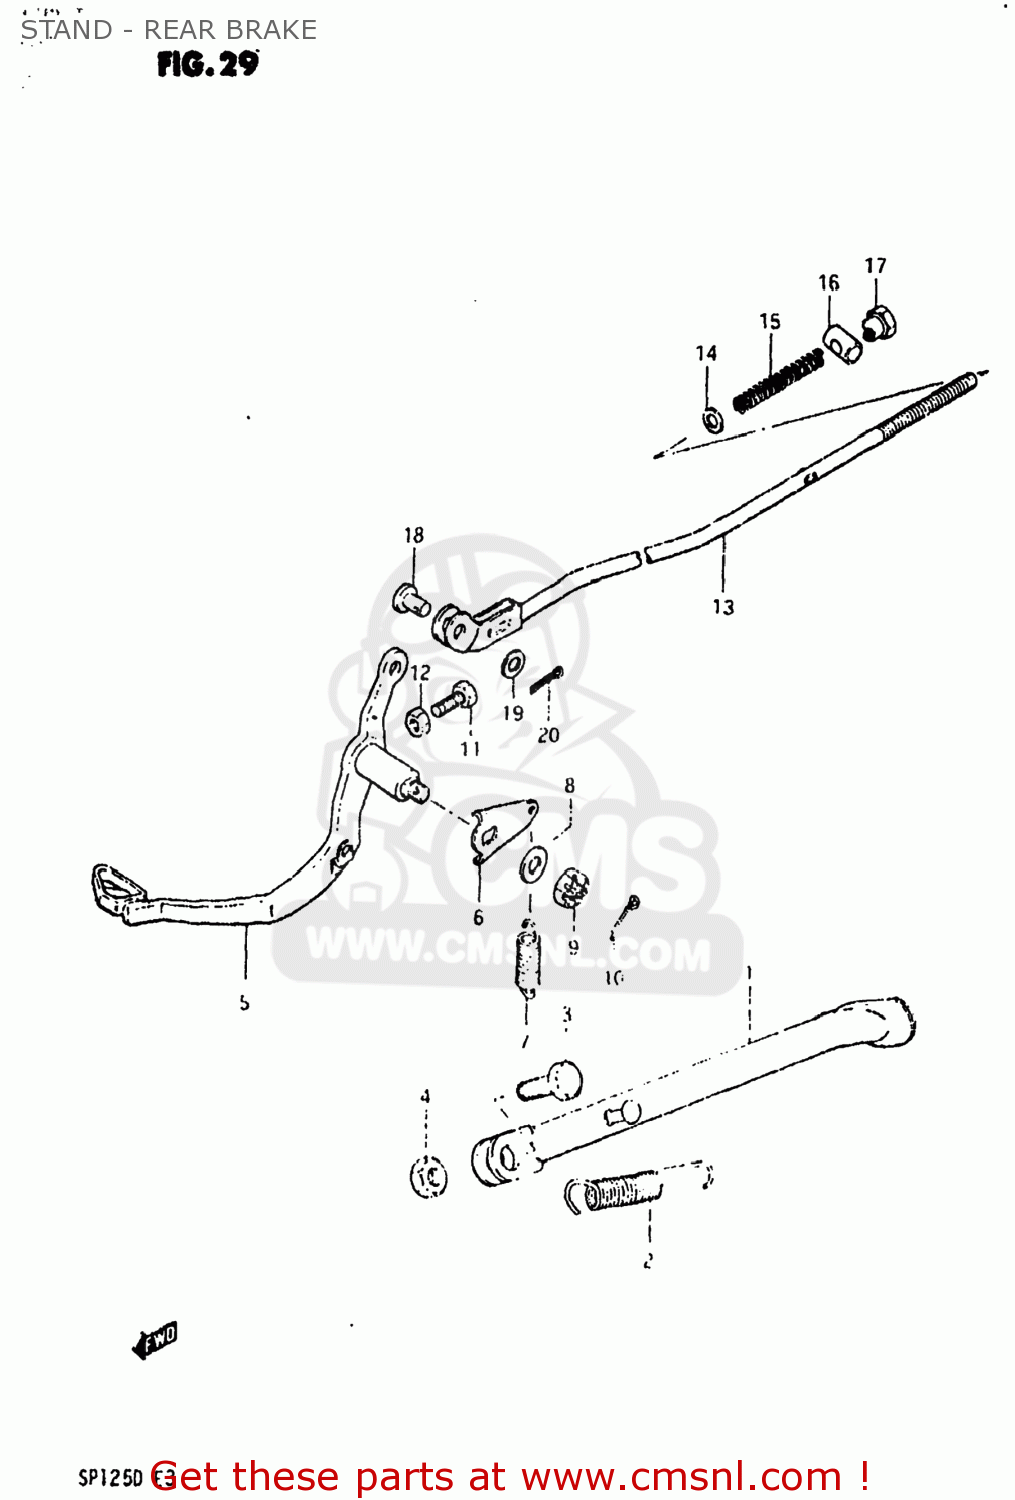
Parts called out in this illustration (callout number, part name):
1	STAND,SIDE
2	SPRING
3	BOLT(10X30)
4	NUT
5	PEDAL,BRAKE
6	ARM,BRAKE RETURN SPRING
7	SPRING
8	WASHER
9	NUT 8MM
10	PIN 20X20
11	BOLT(6X23)
12	NUT
13	ROD ASSEMBLY,REAR BRAKE
14	WASHER
15	SPRING
16	PIN
17	NUT
18	PIN
19	WASHER
20	PIN 20X20
